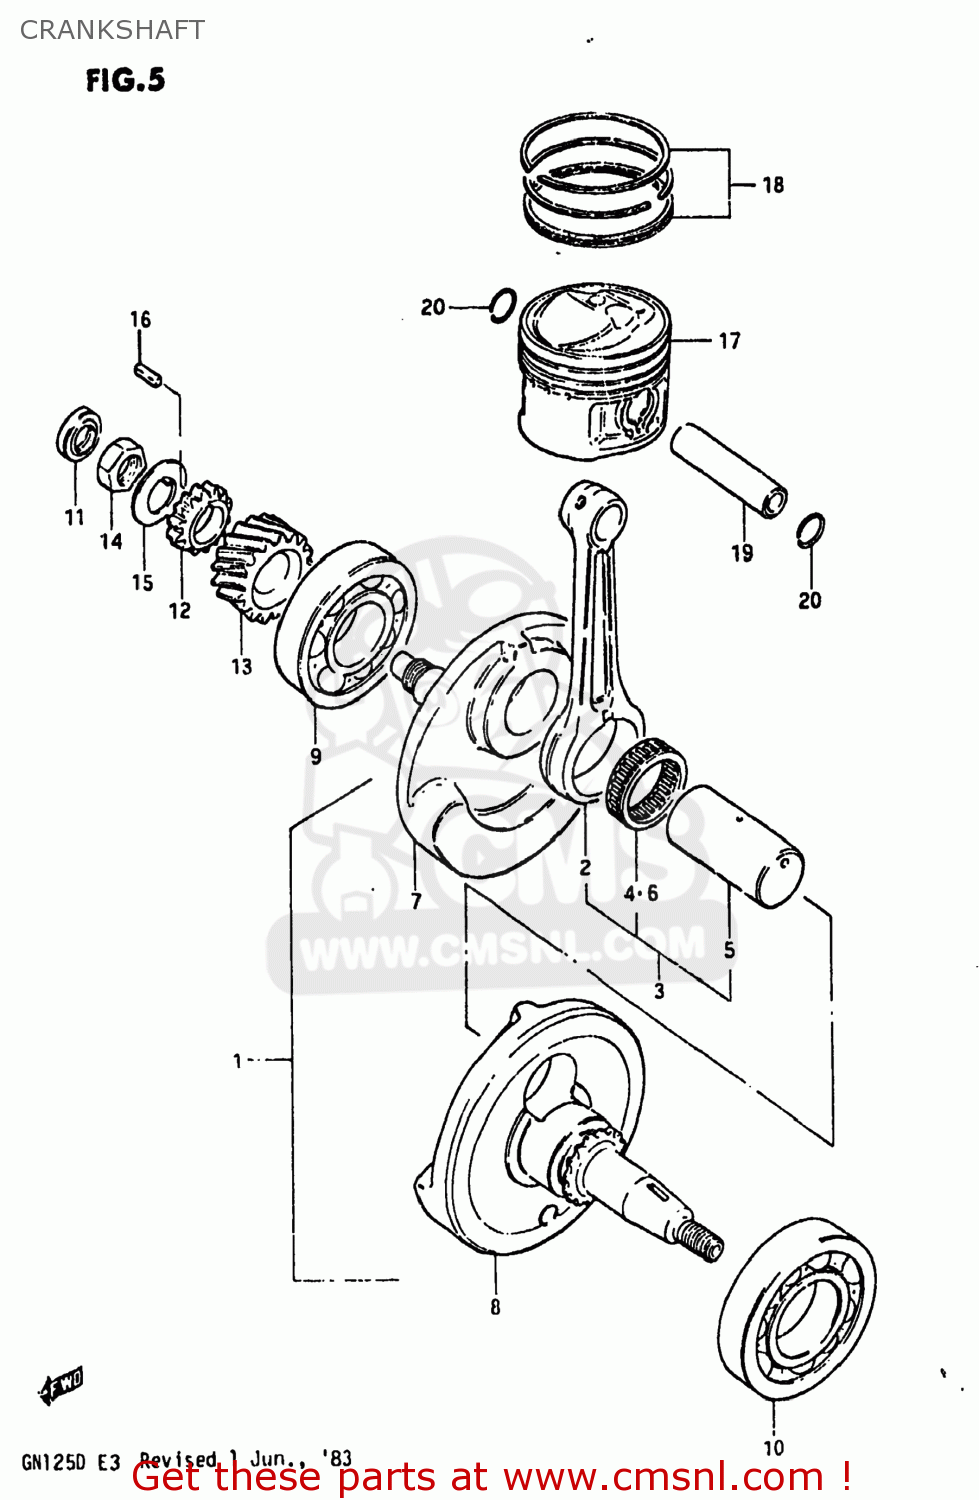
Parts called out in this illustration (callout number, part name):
1	CRANKSHAFT ASSEMBLY
2	CONNECTING ROD
3	CRANKSHAFT ASSEMBLY
4	BEARING
5	PIN,CRANK
6	BEARING
7	CRANKSHAFT
8	CRANKSHAFT,LEFT
9	BEARING,MIDDLE
10	BEARING,LEFT
11	OIL SEAL
12	GEAR,OIL PUMP DRIVE
13	GEAR,PRIMARY DRIVE
14	NUT
15	WASHER
16	KEY
17	PISTON (STD)
18	RING SET,PISTON
19	PIN,PISTON
20	RING,SNAP 14MM
